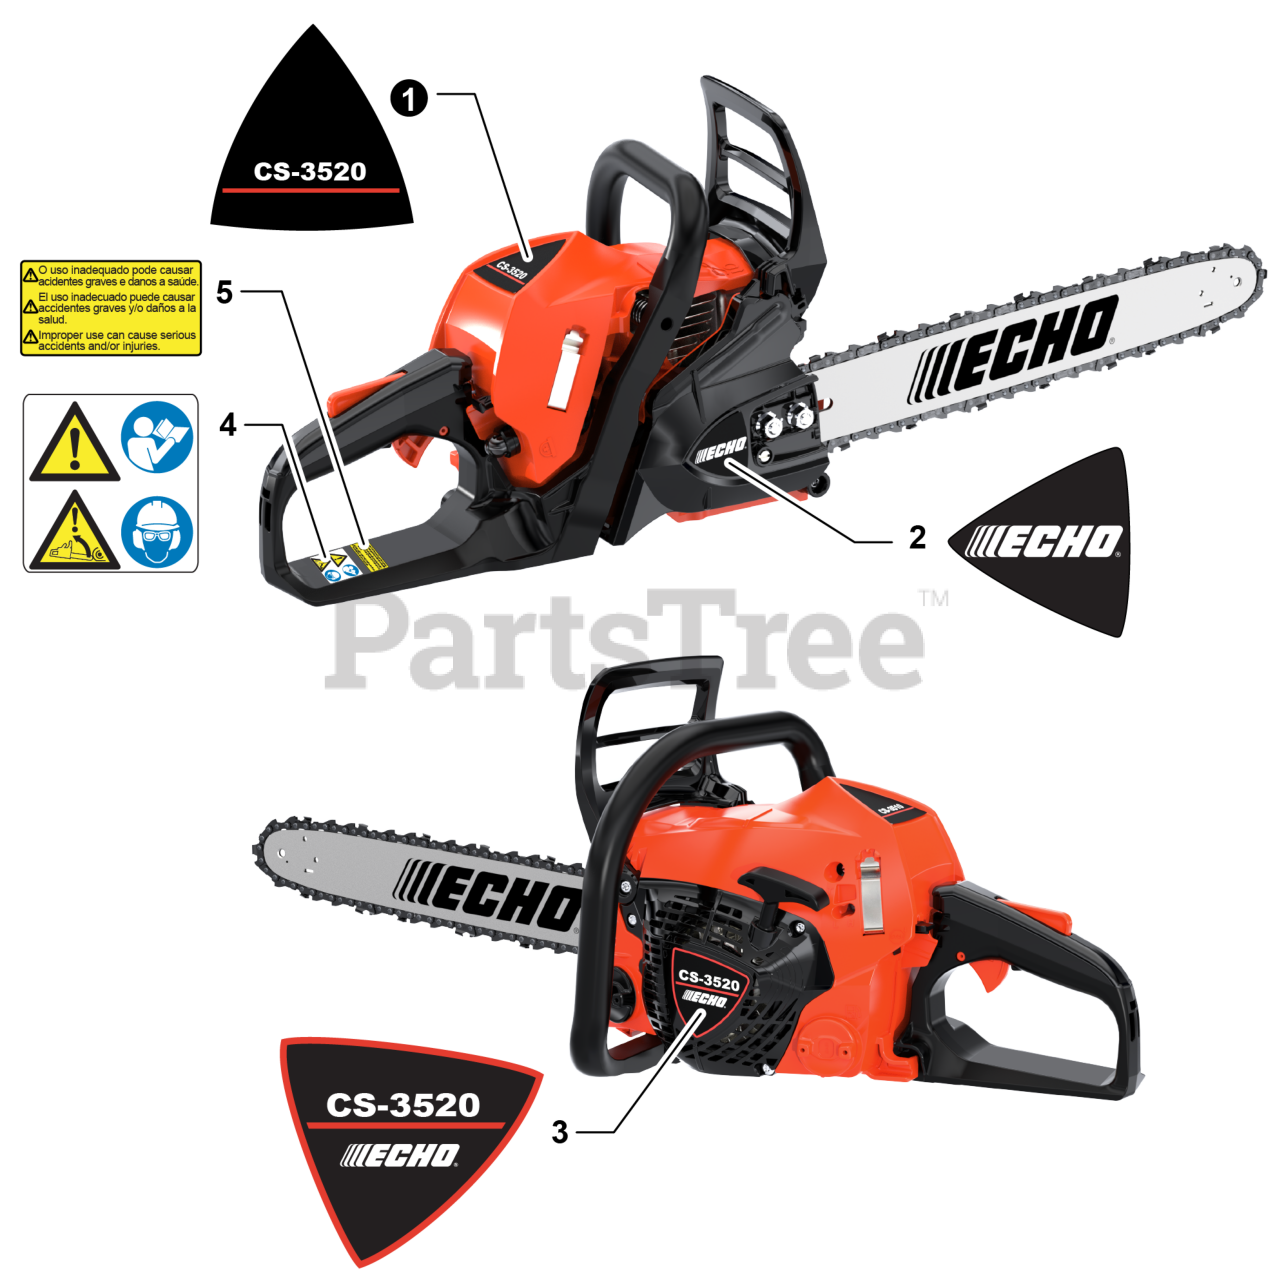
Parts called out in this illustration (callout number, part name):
1	LABEL - MODEL CS-3520
2	LABEL - ECHO
3	LABEL - RECOIL STARTER
4	LABEL - CAUTION
5	LABEL - CAUTION
